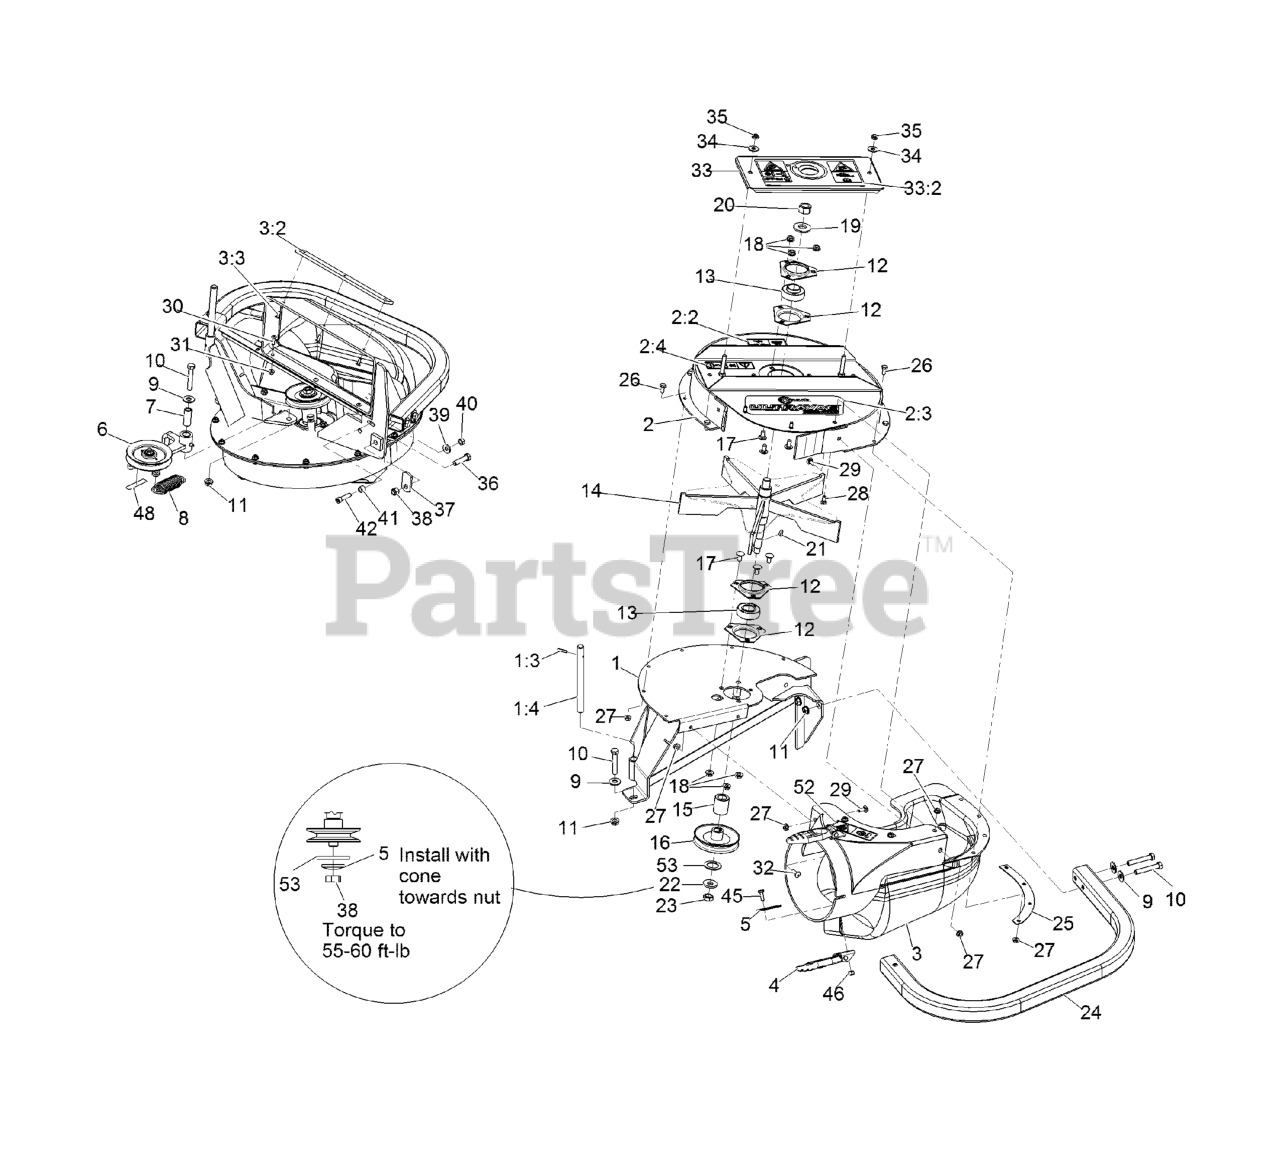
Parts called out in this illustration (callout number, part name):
1	WLD,FRAME LG BLOWER
1:3	PIN-ROLL
1:4	SHAFT-CATCHER, GRASS
2	ASM-UPPER HOUSING LARGE
2:2	DECAL-WARNING, TRACTION
2:3	DECAL-ULTRAVAC X-SERIES
2:4	DECAL-COVER, MISSING
3	ASM,BLOWER CHUTE LZ
3:2	PLATE,REINFORCEMENT LARGE
3:3	RIVET-BLIND
4	LATCH-RUBBER
5	PLATE-BACKING
6	ASM, Idler
7	BUSHING
8	SPRING-IDLER
9	WASHER-FLAT
10	SCREW-HH
11	NUT-HHF, WHIZ
12	HOUSING-FLANGE
13	BEARING
14	IMPELLER
16	SHEAVE
17	SCREW-CARR
19	WASHER-SPRING
20	NUT-HEX
21	KEY-WOODRUFF
22	WASHER-SPRING
23	NUT-JAM
25	PLATE-BACKING, BLOWER
26	SCREW-HH
28	SCREW-CARR
29	BOLT-CARR
30	SCREW-HEAD, TRUSS
33	ASM, BEARING COVER
33	COVER, BEARING
33:2	DECAL-WARNING, BLOWER
34	WASHER-FLAT
35	NUT-LOCK, NI
36	SCREW-HH
37	LATCH-CATCHER, GRASS
38	NUT-LOCK, NI
39	WASHER-SPRING
40	NUT-HEX
41	BUSHING, LOCATOR
42	SCREW-HSH
45	SCREW-HH
46	NUT-LOCK, NI
48	DECAL-WARNING
52	Decal-Blower-Impeller Hazard
53	WASHER-SPACER
